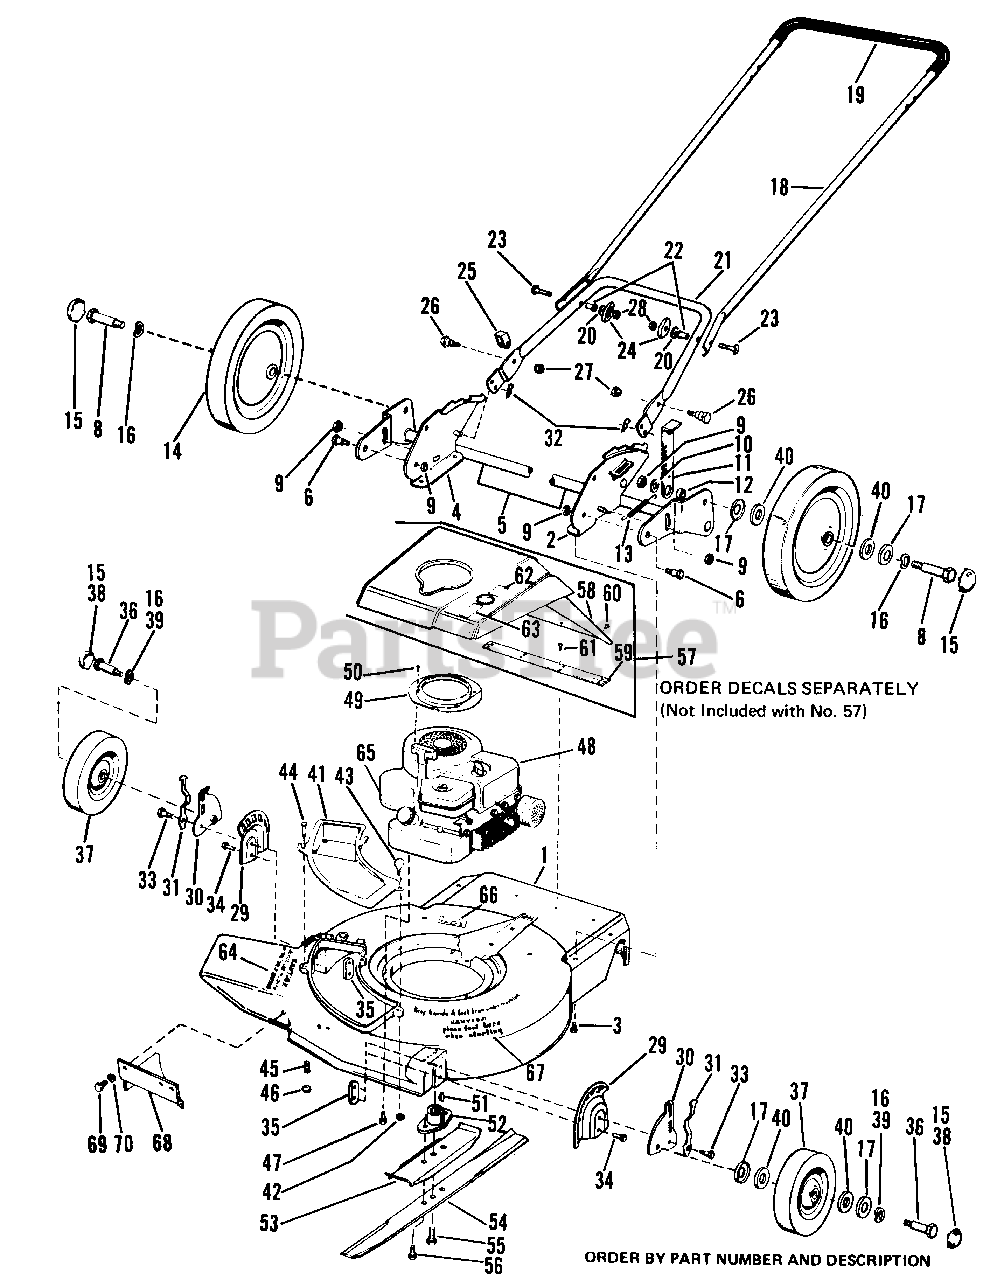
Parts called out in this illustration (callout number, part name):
1	HOUSING, 21"
2	BRACKET ASSY, L.H.
3	WASHER, Hex Hd., Taptite, 1/4-20 x 3/8
4	BRACKET ASSY, R.H.
5	PLATE & TUBE ASSY
6	BOLT, Shoulder, Hex
7	SEAL, Housing
8	BOLT, Rear Wheel
9	NUT, Hex, Full Lock, 3/8-16 (Qty. 1 of 5 used on all models)
9	NUT, Hex, Flange Lock, 5/16-18
10	WASHER, Plain, 5/16
11	ADJUSTER, Height Rear
12	SPACER, Height Adj.
13	SPRING, Height Adj.
14	WHEEL, 10" Rear
15	CAP, Hub, Rear
15	CAP, Hub, Front & Rear
16	WASHER, Wave
17	SEAL, Housing
18	HANDLE, Upper
19	TUBING, Handle
20	WASHER, Plain, 1/4
21	HANDLE, Lower
22	EYELET, Handle
23	BOLT, Curved Hd. 5/16-18 x 1-3/4
24	NUT, Wing
25	LATCH, Handle
26	BOLT, Latch, Handle
27	NUT, Latch, Handle
28	NUT, Hex, Full Lock, 5/16-18
29	PLATE, Adjusting
30	ADJUSTER, Height, Front
31	SPRING, Height Adj.
32	CLIP, Hairpin
33	BOLT, Shoulder, Hex
34	CAPSCREW, Hex, 3/8-16 x 5/8
35	NUT, Pilot, Twin
36	BOLT, Front Wheel
37	WHEEL, 6" Front
38	CAP, Hub (990679, 990856 Front Only)
39	WASHER, Spring
40	WASHER, Seal
41	PLATE, Cover
42	NUT, Speed, Special
43	SCREW, Thumb, 1/4-20 x 5/8
44	SCREW, Special
46	NUT, Full Lock, 1/4-20
47	SCREW, Thd. Forming, 3/8-16 x 1
49	RING, Support
50	RIVET, Rd. Hd., 3/32
51	KEY, Woodruff #6, 5/32 x 5/8
52	ADAPTER, Blade
53	STIFFENER, Blade
54	BLADE, 21"
55	CAPSCREW, Hex, 3/8-24 x 1-1/2
56	BOLT, 5/16-18 x 1 (Blade to Adpt.)
57	SHROUD ASSY
60	RIVET, Oval Hd. 3/16 x 5/16
61	SCREW, Thd. Forming #12-24 x 1/2
62	FILM, Simplicity
63	FILM, Throttle Control
64	FILM, Instruction
65	FILM, Numeral, Engine
66	PLATE, I.D. No.
67	DECAL, Safety Stds.
68	GUARD ASSY, Stone
69	CAPSCREW, Hex Hd., 1/4-20 x 1/2
70	LOCKWASHER, 1/4
